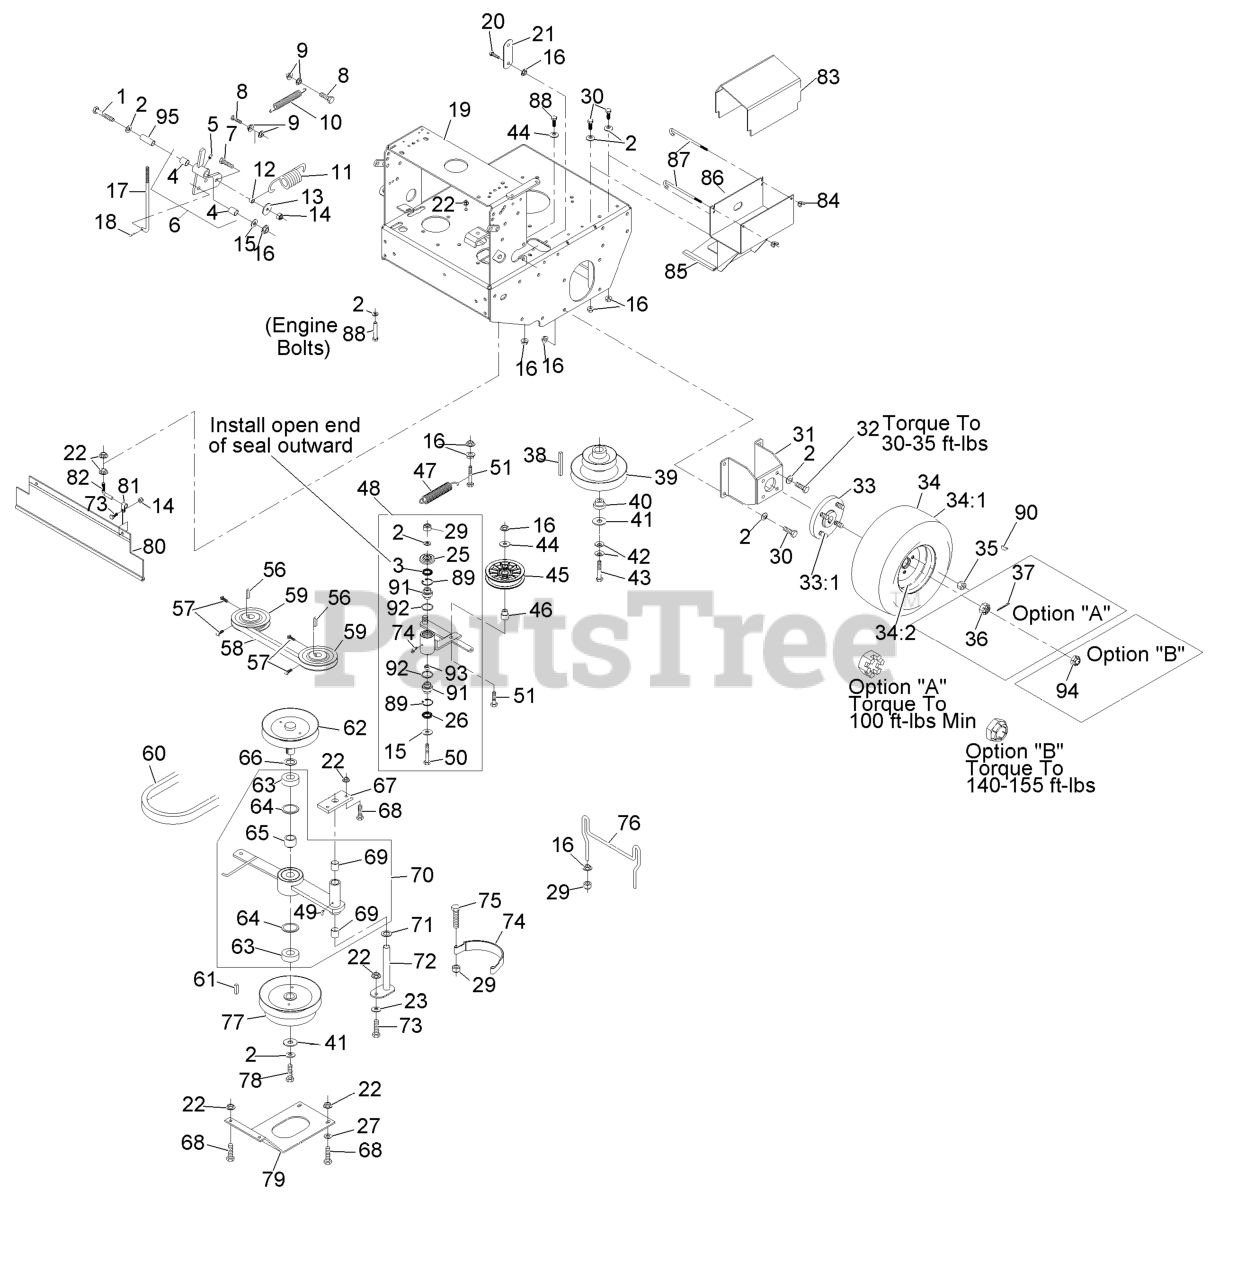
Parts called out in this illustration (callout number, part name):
1	SCREW-HH
2	WASHER-BELLEVILLE
3	SEAL-LIP, SINGLE
4	SLEEVE-BEARING
5	FITTING-GREASE
6	ASM,PIVOT W/BUSHINGS
7	SCREW-HH
8	SCREW-HH
10	SPRING,EXTENSION
11	SPRING,EXTENSION
12	SPACER,CLUTCH ANCHOR
14	NUT-LOCK, NI
15	WASHER-FLAT
16	NUT-HHF, WHIZ
17	LINKAGE,LOWER
18	PIN-COTTER
19	KIT,TTHP ENG DECK
20	SCREW-HH
21	ARM-LIFT, DECK
23	WASHER-SPRING
25	GUARD-TOP
26	SEAL-LIP, DOUBLE
27	WASHER-FLAT
29	NUT-LOCK, NI
30	SCREW-HH
31	WLD,MOTOR MOUNT 48&52
32	SCREW-HH
33:1	STUD-WHEEL
34	WHEEL AND TIRE ASM
34:1	TIRE-TURFMASTER
34:2	RIM-WHEEL
35	NUT-LUG
36	NUT-HEX, SLOTTED
37	PIN-COTTER
38	KEY,MACH 1/4X1/4X2-5/8
39	SHEAVE, DRIVE
40	BUSHING,CLUTCH KEEPER
42	WASHER-SPRING
43	SCREW-HH
44	WASHER-FLAT
45	PULLEY-IDLER, FLAT
46	BUSHING-IDLER
48	KIT,PUMP IDLER ARM TTHP
49	FITTING-GREASE
50	SCREW-HH
51	SCREW-HH
57	SCREW-SET
58	BELT,COG A 50.55
59	SHEAVE ASM
60	BELT,B-38.0
62	SHEAVE, W/ SHAFT
63	BEARING,CLUTCH SHAFT
64	RING-SNAP
65	SPACER,CLUTCH BEARING
66	WASHER-SPACER
67	PLATE-CLUTCH PIVOT
68	SCREW-HH
69	SLEEVE,BEARING
70	ASM,CLUTCH ARM W/BEARING
71	WASHER-SPACER
72	WLD,PIN PIVOT
73	SCREW-HH
74	BAND,BRAKE BLADE
75	SCREW-HH
76	GUIDE,BELT (PLTD)
77	SHEAVE,6.75 W/DRUM
78	SCRW,CAP HH
79	PLATE-GUARD
80	SHIELD-DRAG
81	CLIP-LOOM
82	MOUNT,DRAG SHIELD
84	WINGNUT
85	TRIM-LOK
86	ASM,BATTERY STAND W/TRIM
87	BOLT - HOLD DOWN
88	SCREW-HH
89	RING-SNAP
90	KEY-WOODRUFF
91	BEARING-SPHERICAL
94	NUT-LOCK
95	BUSHING
